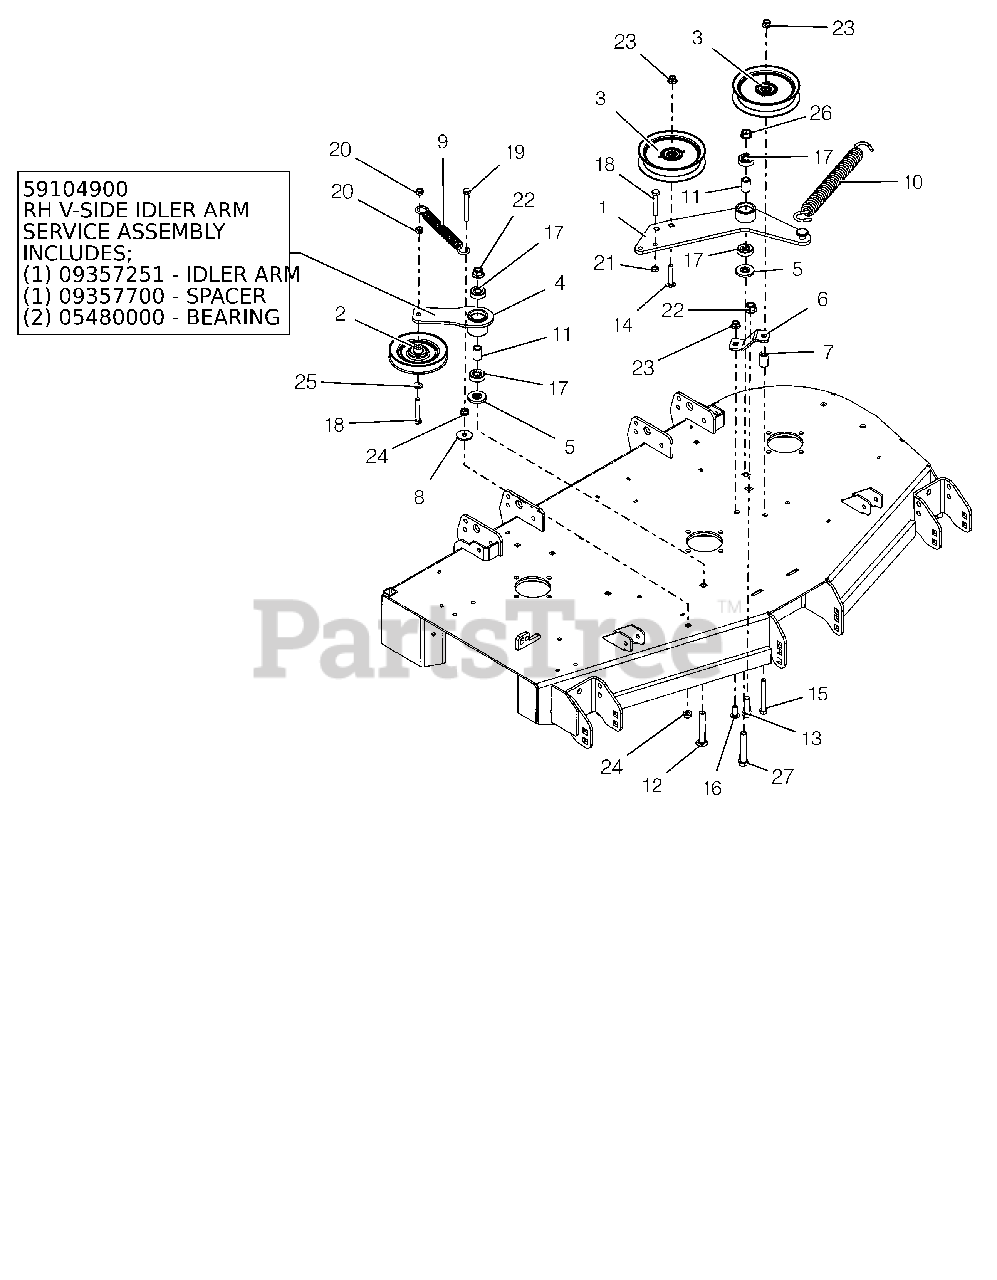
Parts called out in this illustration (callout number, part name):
1	DECK PTO IDLER ARM WLDMT - BLK
2	IDLER, V-5.00"
3	IDLER, FLAT 5.00"
4	DECK RH IDLER ARM WMT - BLK
4	RH V-SIDE IDLER ARM ASSEMBLY
4	SPACER .510 X .75 X 1.1485
4	BRG-BALL .50X1.38X.438 SEALED
5	SPACER, IDLER ARM
6	PTO FIXED IDLER MTG BRKT -RED
7	BUSHING, SLV .380X.750X1.190
8	WSHR-FL-STL .406X1.375X.135 YZ
9	SPRING, EXTENSION
10	SPRING, EXTENSION
11	SPACER .510 X .75 X 1.1485
12	BLT,RDHDSQSHNK.50-13X3.25 G5YZ
13	@BLT-HEX .50-13X1.50 GR5 YWZC
14	BLT-RDHDSQNK .38-16X2.00 SHTYW
15	@BLT-HEX .38-16X3.25 GR5 YWZC
16	@BLT-RDHDSHSQNK.38-16X1.0 G5YZ
17	BRG-BALL .500X1.38X.437
18	@BLT-HEX .38-16X2.25 GR5 YWZC
19	@BLT-HEX .38-16X3.00 GR5 YWZC
20	@NUT-LK-CTR .38-16 YWZC
21	NUT-HEX-JAM .375-16 YWZC
22	@NUT-LK-NYL-FLG .50-13 YWZC
23	@NUT-LK-NYL-FLG .38-16 YWZC
24	@NUT-SPNLK-FLG .375-16 YWZC
25	@WSHR-FL-STL.406X.812X.065 YWZ
26	NUT-LK-CTR-FLG .50-13 YWZC
27	@BLT-HEX .50-13X3.00 GR5 YWZC
